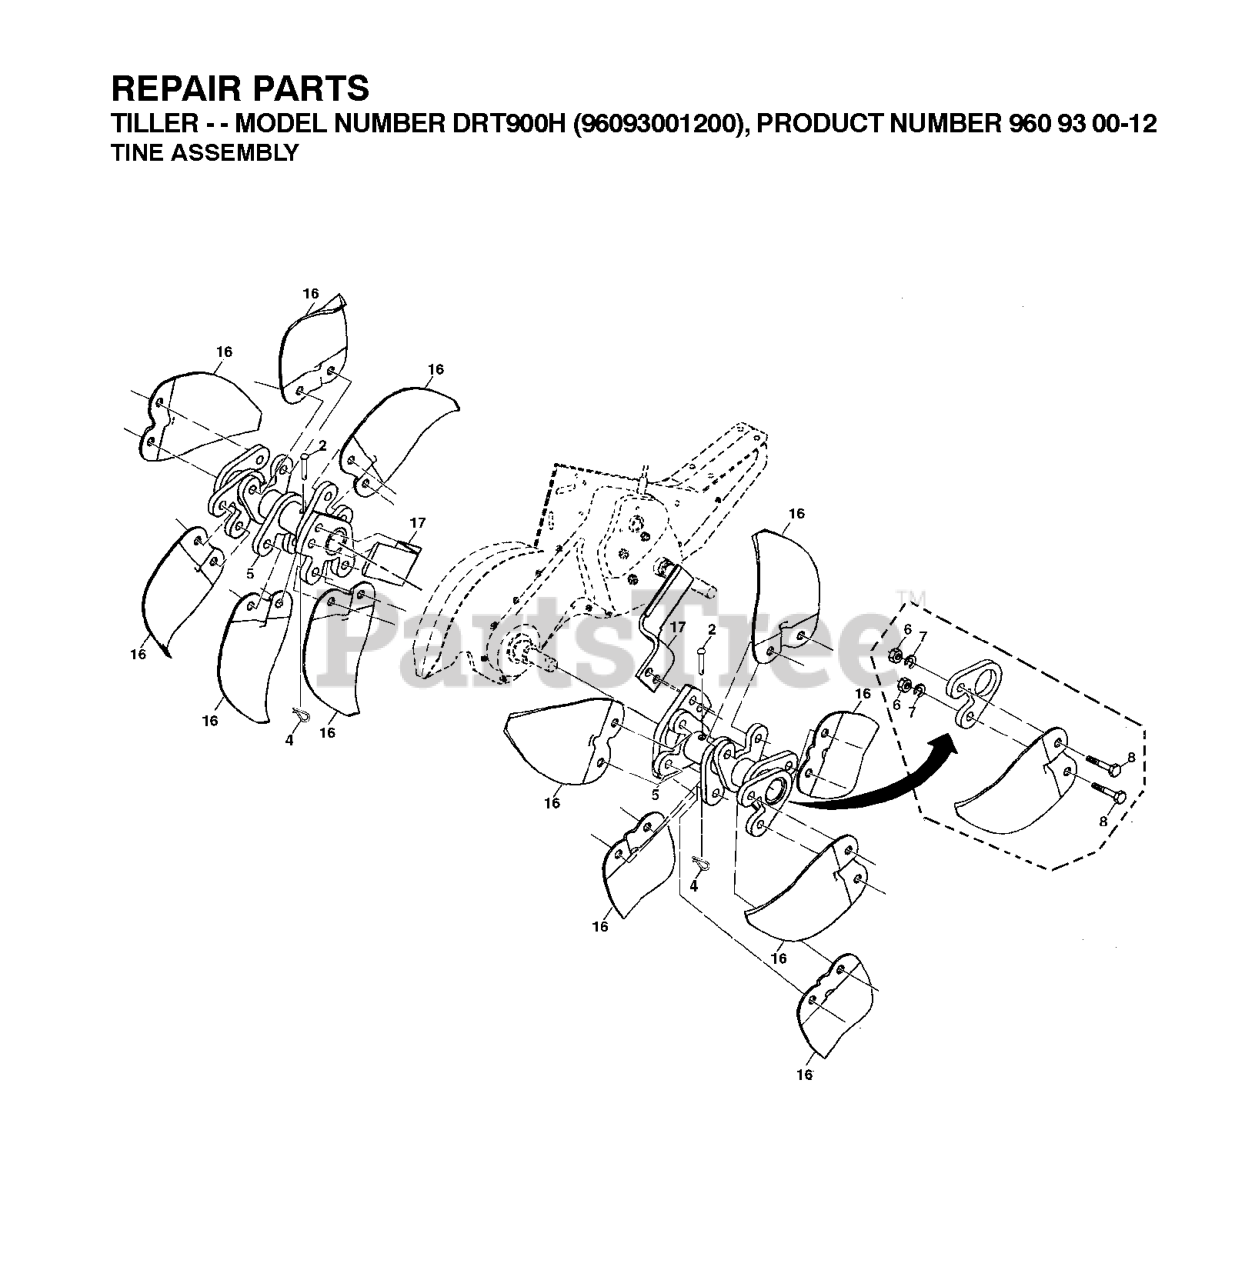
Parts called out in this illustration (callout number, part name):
2	PIN RETAINING SCREW
4	SPRING RETAINER
5	HUB.ASM.DRT17.2004 (CMPL KIT)
6	NUT
7	WASHER, LOCK 3/8
8	BOLT.HEX.001X20.37-24X1.ZINC
16	TINE.SPADE
17	TINE.CLEANING BLACK
